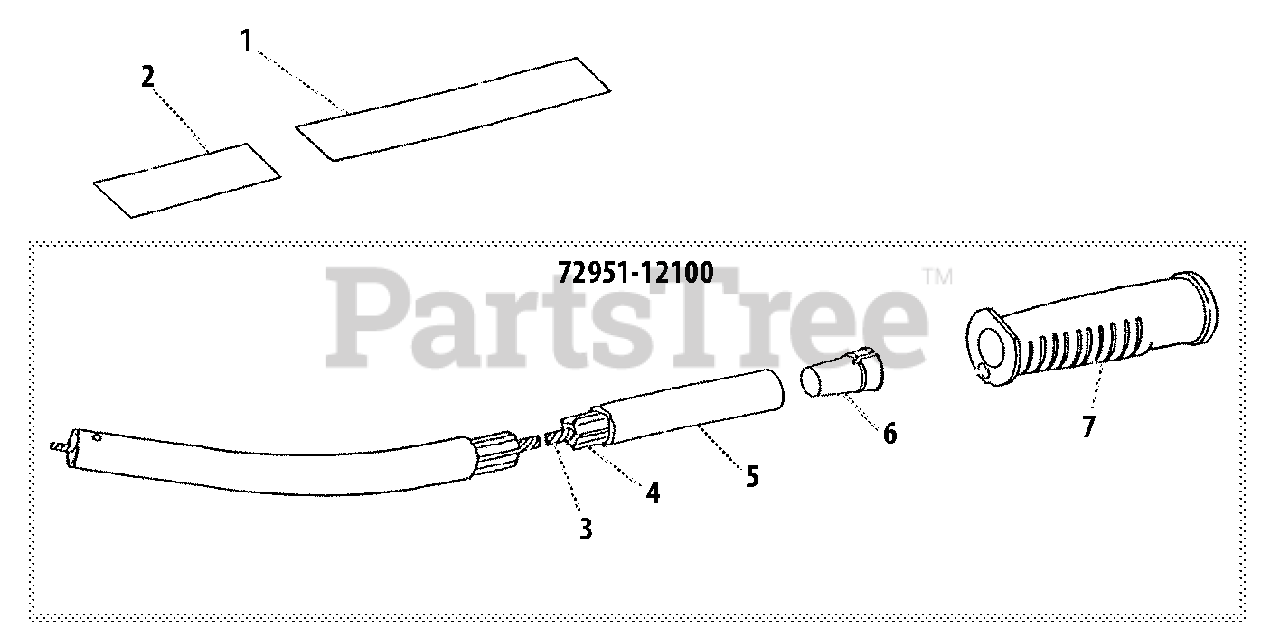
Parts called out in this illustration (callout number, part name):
1	LABEL - MODEL
2	LABEL - CAUTION
3	DRIVESHAFT - FLEXIBLE
4	LINER - FLEXIBLE
5	MAIN PIPE ASSY
6	GUIDE, SHAFT
7	GRIP - REAR
72951-12100	MAIN PIPE ASSY
